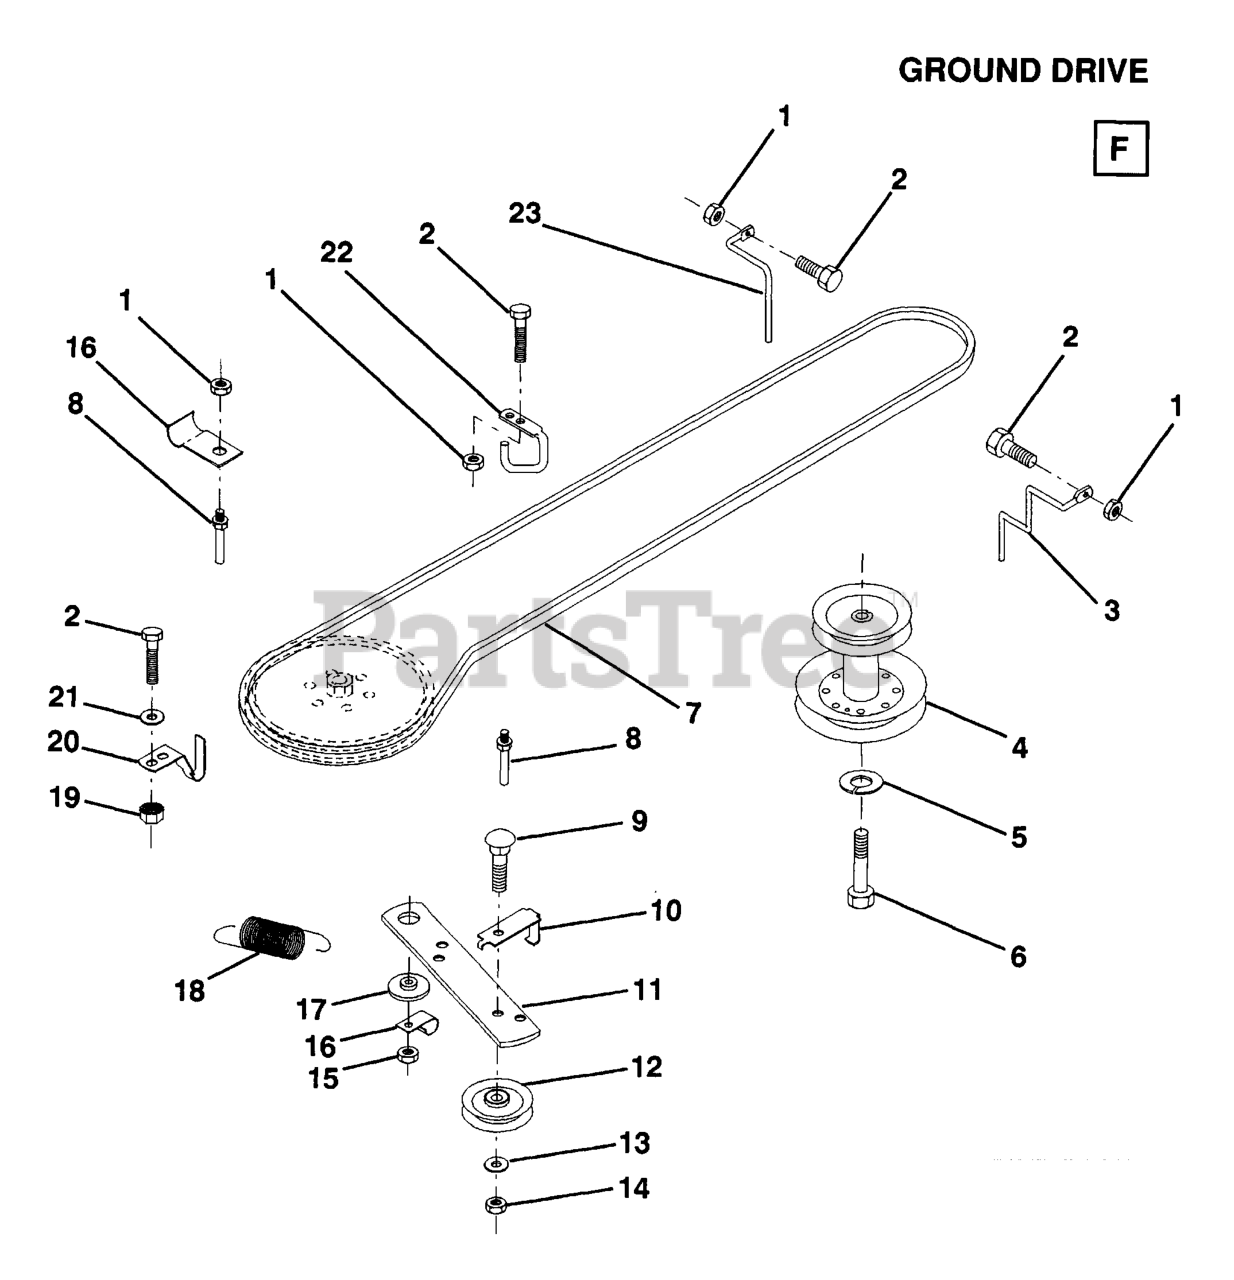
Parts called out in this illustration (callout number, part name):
1	LOCKNUT
2	BOLT
3	KEEPER MWR DRV RH
4	PULLEY
5	LOCKWASHER
6	Soft, Fin. Hex 7/16-20 UNF x 1-1/4 Gr. 8
7	BELT
8	KEEPER,DRIVE BELT
9	Bolt, Carriage 3/8-16 UNC x 1-1/2
10	KEEPER.BELT.GROUND.DRIVE.IDLER
11	ARM,DR CLUTCH GRO
12	FLAT IDLER PULLEY
13	WASHER
14	LOCKNUT
16	CLIP,INSULATOR
17	SPACER RETAINER
18	SPRING.EXTENSION
19	LOCKNUT
20	KEEPER,DR BELT GR
21	WASHER
22	KEEPER,FRA DR BEL
23	KEEPER MWR DRV LH
